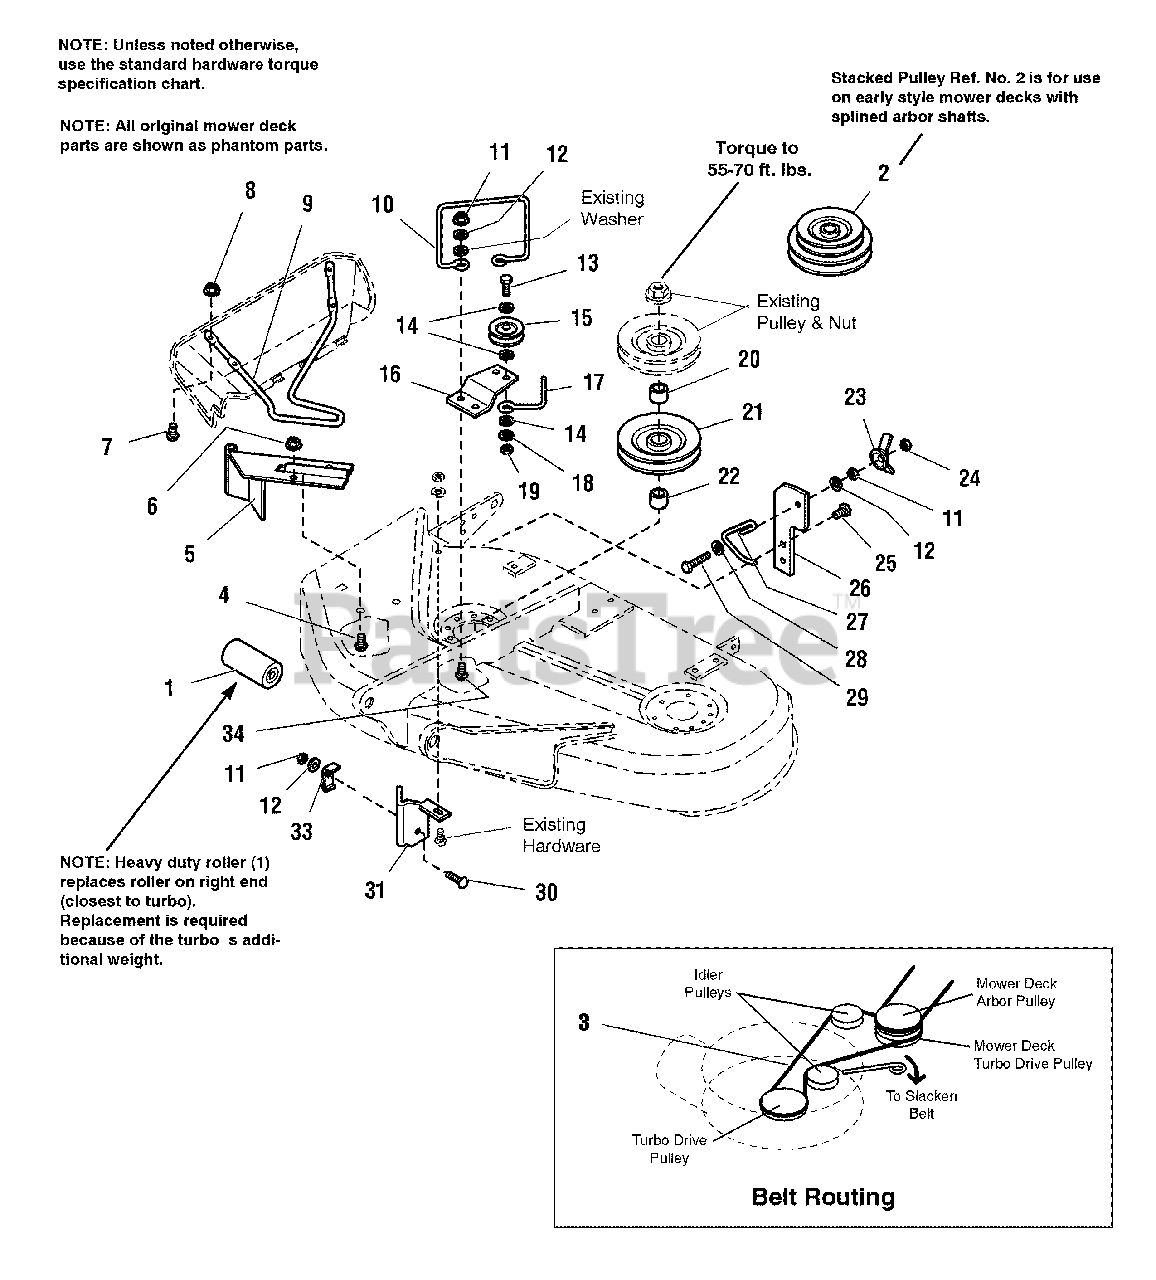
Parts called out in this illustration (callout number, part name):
2	STACKED PULLEY ASSY
4	CARRIAGE BOLT, 5/16-18 x 3/4
5	PIVOT ASSY.
6	NUT, Hex, Flange, Whizlock, 5/16-18
7	SCREW, Truss Hd., #10-24 x 3/4
8	NUT, Nylock, #10-24
9	ROD, Deflector
10	BELT GUIDE, Turbo
11	NUT, Hex, 5/16-18
12	LOCKWASHER, 5/16
13	CAPSCREW, 3/8-16 x 1-1/4
14	WASHER, Flat, 3/8
15	IDLER PULLEY
16	BRACKET, Idler
18	LOCKWASHER, 3/8
19	NUT, Hex, 3/8-16
20	SPACER, Splined, 1.590" Long
21	PULLEY ASSY.
22	SPACER, Short
23	NUT, Wing Assy, 5/16
24	NUT, Hex, Center Lock, 5/16-18
25	SCREW, Taptite, 5/16-18 x 1/2
26	BRACE,
27	SPRING LATCH
28	WASHER, Flat
29	CAPSCREW, Hex Hd, 5/16-18 x 2-1/2
30	CARRIAGE BOLT, 5/16-18 x 1-1/4
31	BRACKET ASSY.
33	BRACKET, "L"
34	SCREW, Taptite, 5/16-18 x 1-1/2
